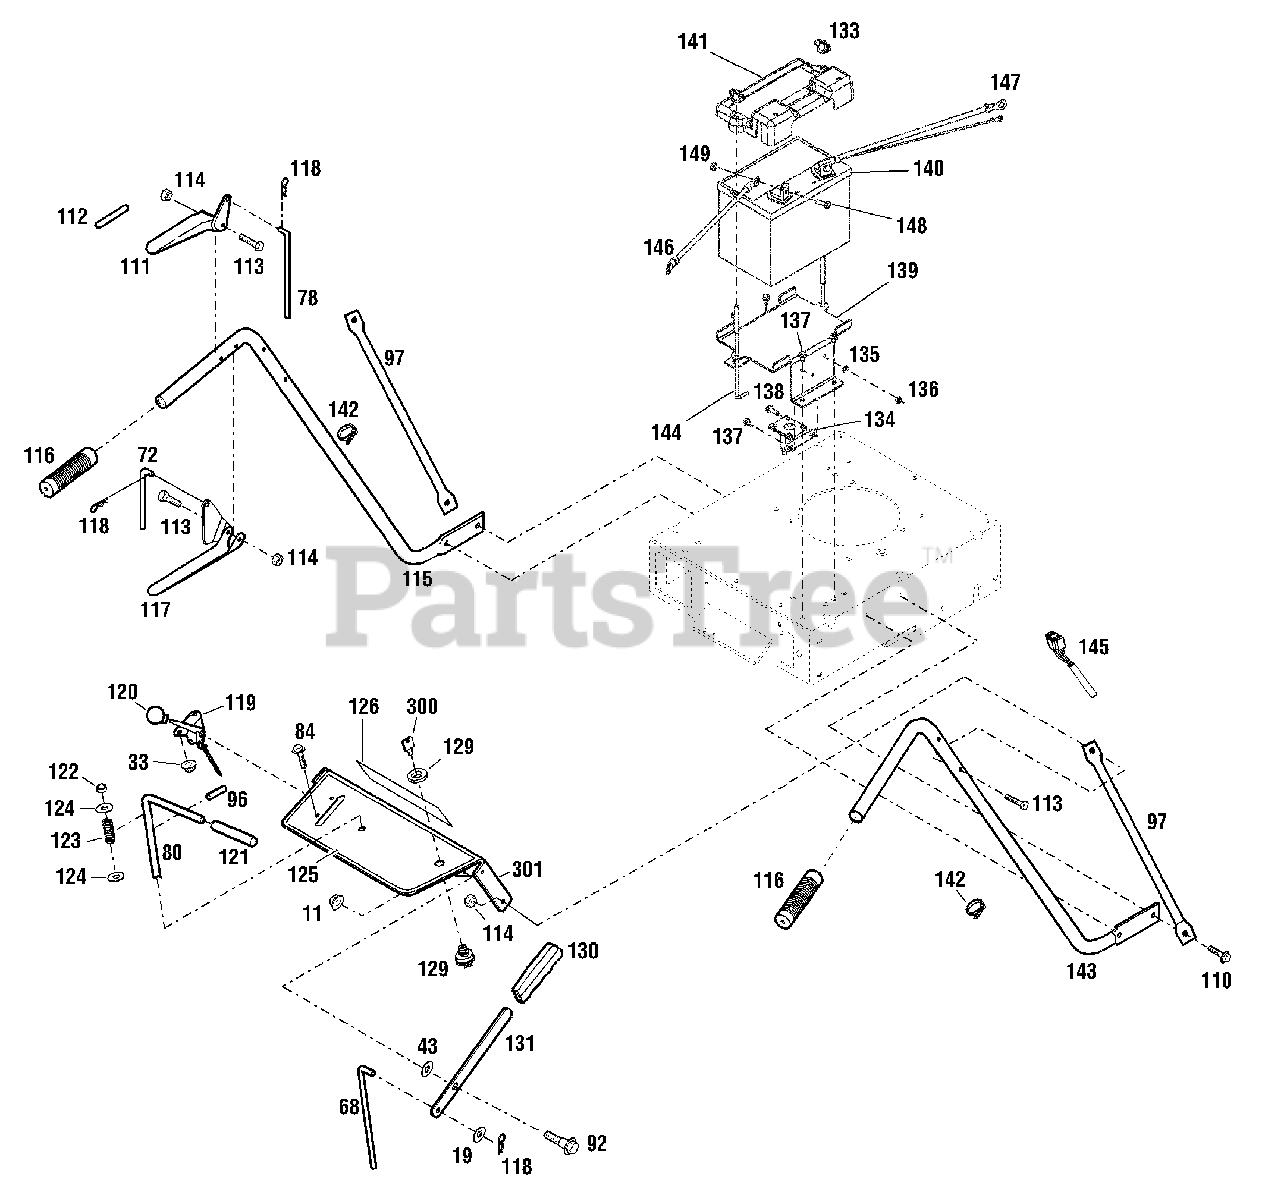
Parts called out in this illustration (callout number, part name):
11	Flange Locknut, 3/8-16
19	Flat Washer, 5/16
33	Flange Locknut, 1/4-20
43	Flat Washer, 1/2
68	Upper Blade Rod
72	Upper Transmission Rod
78	Upper Brake Rod
80	Shift Rod
84	Flange Lock Screw, 1/4-20 x 1/2
92	Shoulder Bolt
96	Roll Pin, 1/4 x 2-1/4
97	Brace, Handlebar
110	Flange Lock Screw, 5/16 x 3/4
111	Control Handle
112	Operator Presence Control Decal
113	Screw, 1/4-20 x 1-3/4, Grade 8
114	Locknut, 1/4-20
115	Left Handlebar
116	Handle Grip
117	Control Handle
118	Hair Pin, 5/64
119	Throttle Control
120	Knob
121	Handle Grip
122	Nylon Bushing
123	Compression Spring
124	Flat Washer, 1/2
125	Warning Decal
126	Logo Decal
129	Ignition Switch
130	Handle Grip
131	Mower Engage Lever
133	Wing Nut, 1/4-20
134	Solenoid
135	External Lock Washer, 1/4
136	Jam Nut, 1/4-20
137	Self-tapping Screw, 1/4-20 x 1/2
138	Self-tapping Screw, 1/4-20 x 3/4
141	Battery Cover
142	Plastic Tie
144	Battery Hold-down Rod
145	Wiring Harness
146	Red Wire, 12"
147	Black Wire, 14"
148	Hex Screw, 1/4-20 x .75
149	Hex Sems Nut, 1/4-20
300	Ignition Key
301	Console Assembly
